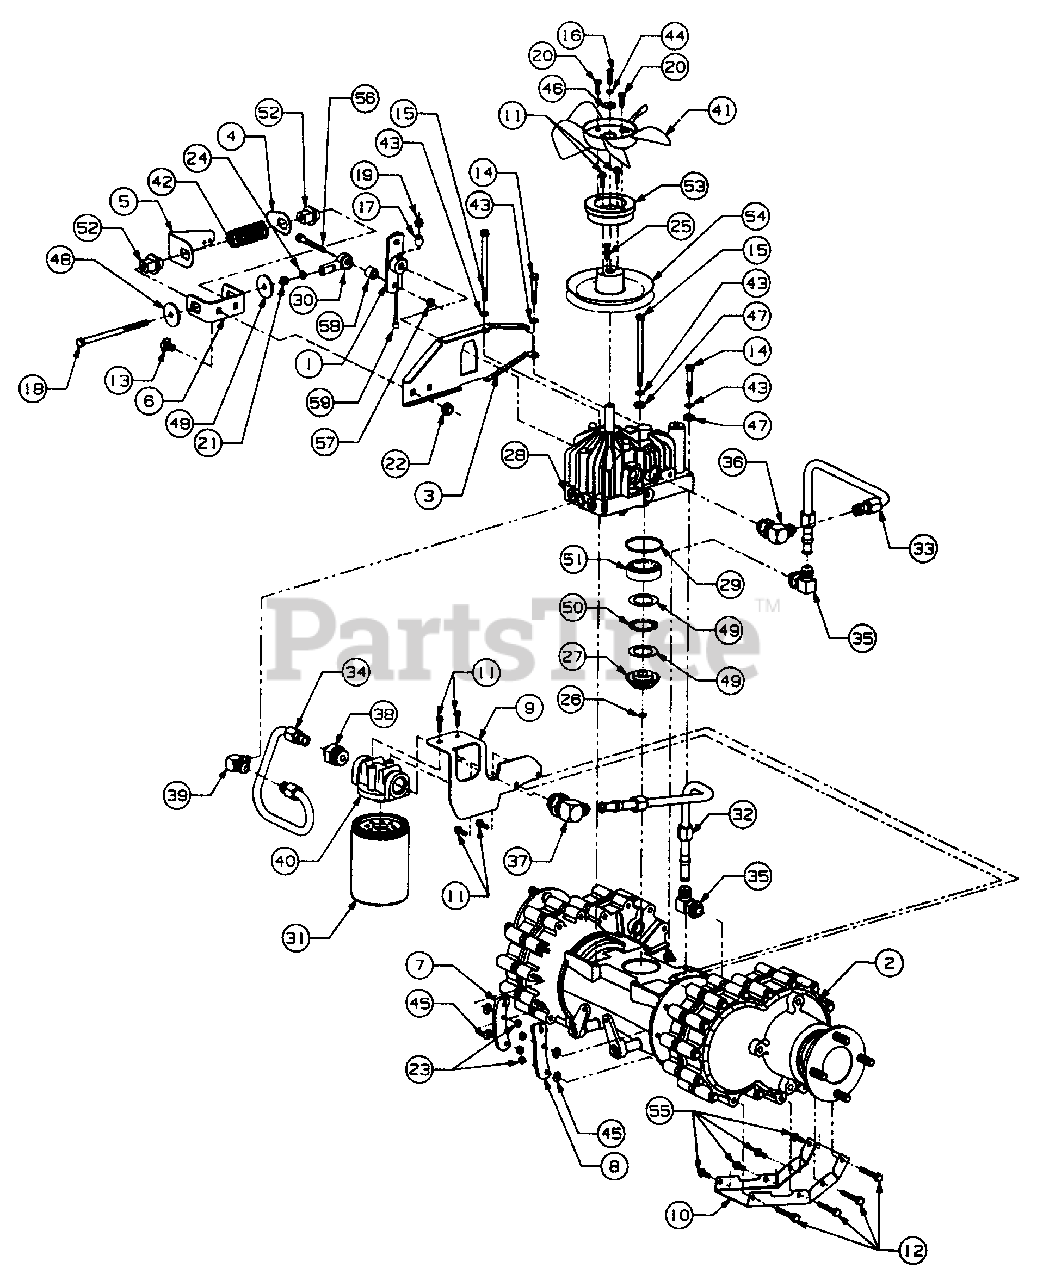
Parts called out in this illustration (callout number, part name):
1	Lever, Forward & Reverse
2	Transmission Assy, Complete
3	Plate, Neutral Mechanism Mtg
4	Stop, Switch
5	Mount, Switch
6	Bracket, Neutral Mechanism
7	Plate, Left Cable Mtg
8	Plate, Right Cable Mtg
9	Bracket, Oil Filter Mtg
10	Plate, Skid
11	Screw, Hex Wash Hd Tapp 1/4-20 X .75 Lg
12	Screw, Hex Wash Hd Tapp 1/4-20 X 2.31 Lg
13	Bolt, Sht Nk Carriage 3/8-16 X .75 Lg GR 5
14	Screw, Hex Cap 5/16-18 X 2.0 Lg GR 5
15	Screw, Hex Cap 5/16-18 X 4.75 Lg GR 5
16	Screw, Hex Cap M6-1.0 X 20mm Lg GR 10.9
18	Screw, Hex Cap 5/16-24 X 5.37 Lg GR 5
19	Nut, Nylon Lock, 10-24
20	Screw, Hex Cap w/Patch 1/4-20 X .75 Lg GR 5
21	Nut, Hex Insert Lock, 5/16-24
22	Nut, Hex Flanged Lock, 3/8-16
23	Nut, Hex Top Lock, 1/4-20
24	Nut, Hex Jam, 5/16-24 GR 5
25	Key, Square 5mm X 5mm X 25mm Lg
26	Ring, Snap, .500 Dia Shaft
27	Gear, Input Pinion -20T
28	Pump, Hydrostatic
29	O-Ring, 2.237 ID X .103 Thk
30	Rod End, Spherical
31	Filter, Oil
32	Tube, Filter Inlet
33	Tube, Return
34	Tube, Hydro Inlet
35	Elbow, 90 Deg w/O-Ring
36	Elbow, 90 Deg w/O-Ring
37	Elbow, 90 Deg w/O-Ring
38	Connector, Straight w/O-Ring
39	Elbow, 90 Deg w/O-Ring
40	Head, Filter
41	Fan, Hydro 8"
42	Spring, Compression 1.20 OD X 2.70 Lg
43	Washer, Lock, 5/16
44	Washer, Lock, 1/4
45	Washer, Flat .25 X .62 X .0515 Thk
46	Washer, Flat .25 X .750 X .119 Thk
47	Washer, Flat .312 X .750 X .119 Thk
48	Washer, Flat .206 X .448 X .105 Thk
49	Washer, Flat 1.25 X 1.937 X .031 Thk
50	Washer, Flat 1.25 X 1.937 X .0781 Thk
51	Spacer, Input Pinion
52	Guide, Neutral Stop
53	Hub, Fan Mtg
54	Pulley, Transmission Drive
55	Screw, Hex Wash. Hd. Tapp 1/4-20 X .50 Lg
56	Screw, Hex Cap 5/16-18 X 1.38 Lg GR 5
57	Nut, Hex Flange Lock 5/16-18 GR 5
58	Spacer .317 ID X .625 OD X .343 Lg
59	Screw, Socket Hd. 10-24 X 1.5 Lg
